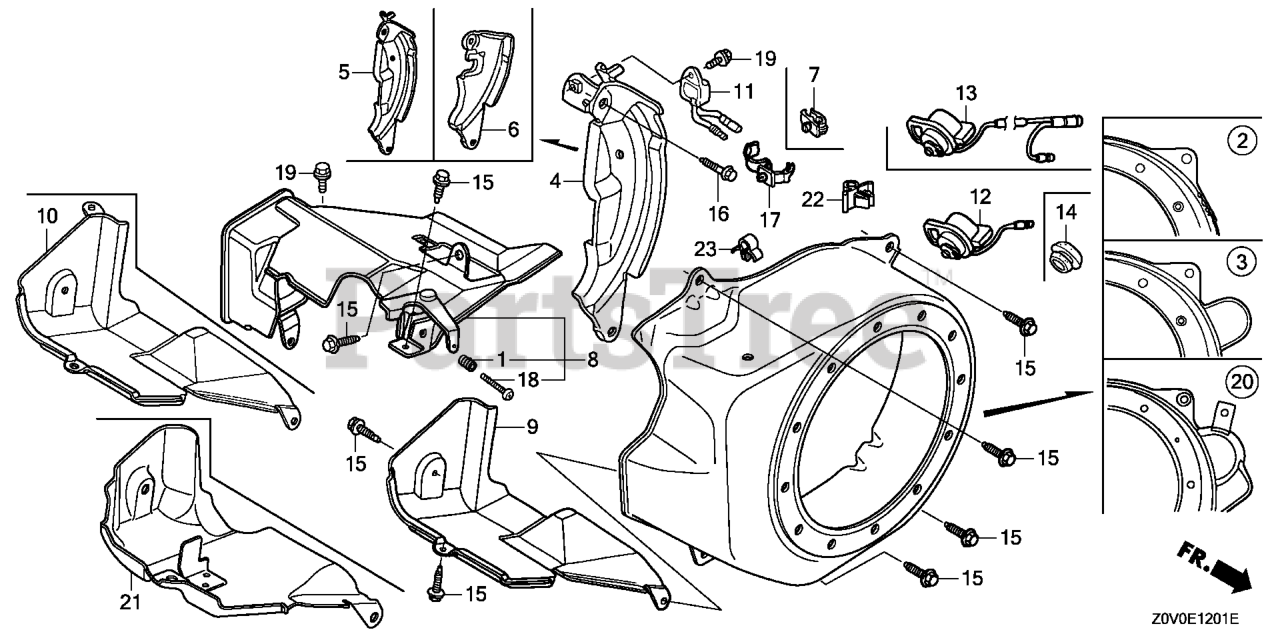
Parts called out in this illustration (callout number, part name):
2	COVER, FAN *R280* (POWER RED)
2	COVER, FAN *NH1* (BLACK)
4	PLATE, SIDE (OIL ALERT)
9	SHROUD
11	ALERT UNIT, OIL (CHONGQING LIHUA)
13	SWITCH ASSY., ENGINE STOP (TOYO DENSO)
13	SWITCH ASSY., ENGINE STOP (MINDA)
15	BOLT, FLANGE (6X12) (CT200)
16	BOLT, FLANGE (6X20) (CT200)
17	CLIP, HARNESS
19	BOLT, FLANGE (6X8)
